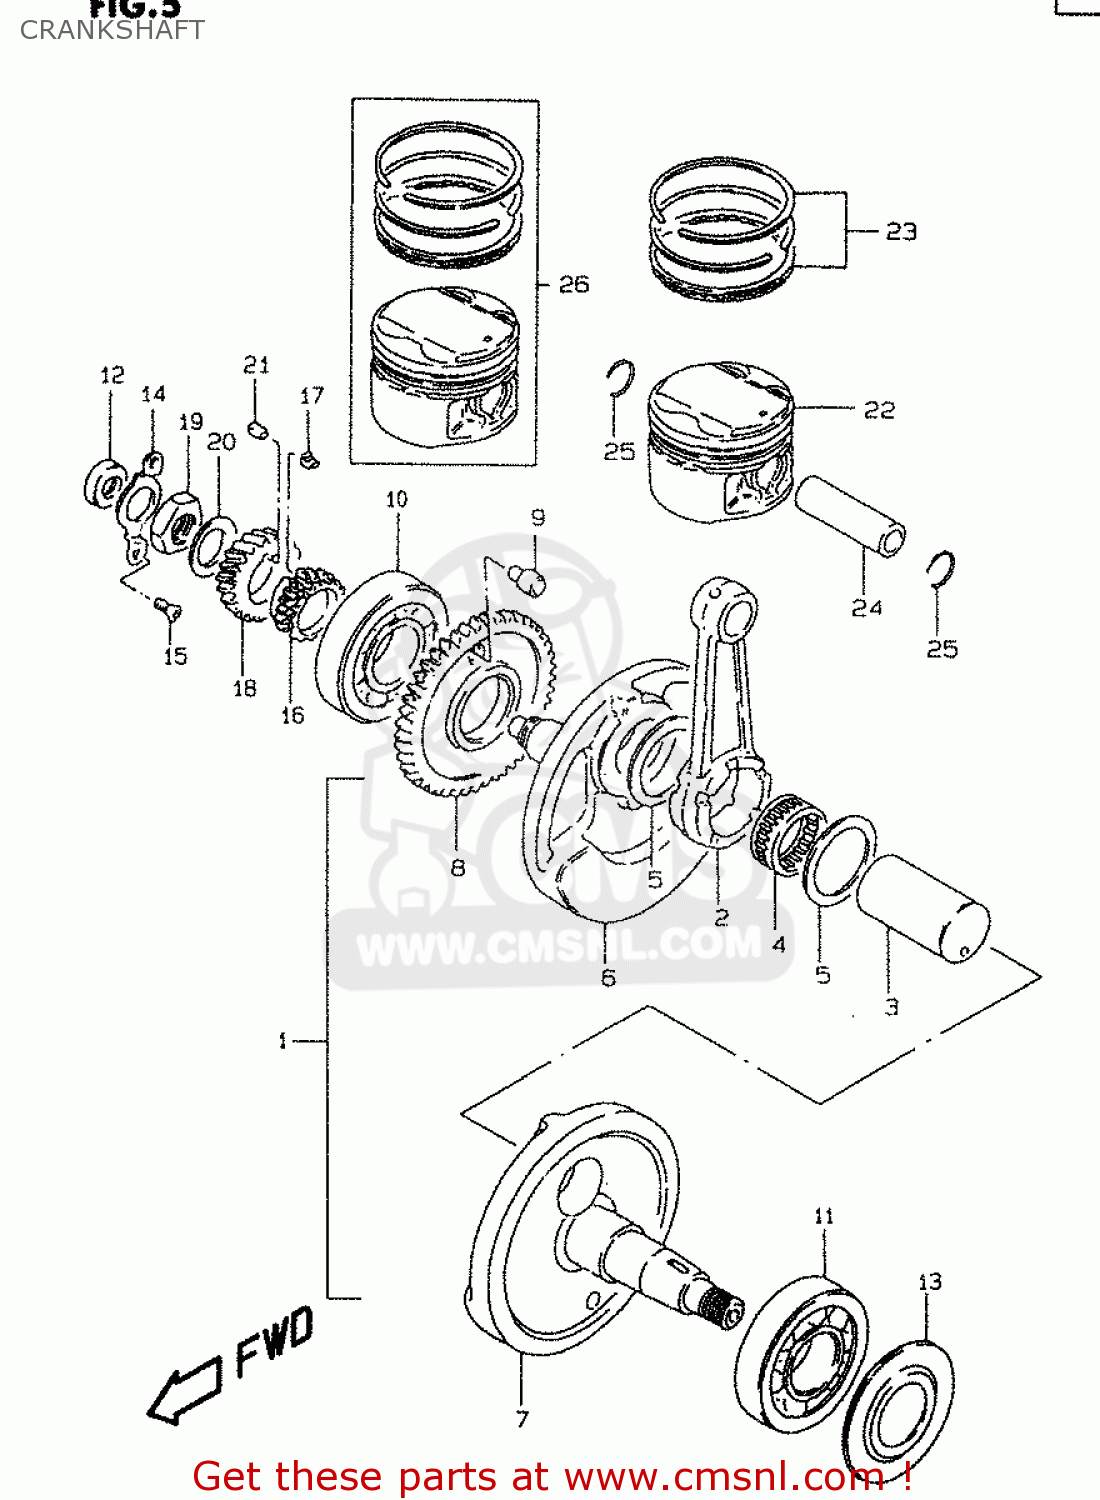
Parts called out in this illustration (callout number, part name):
1	CRANKSHAFT ASSEMBLY
2	ROD,CONNECTING
3	PIN,CRANK
4	BEARING(31X39X21)
5	WASHER(31X48.5X1)
6	CRANKSHAFT,R
7	CRANKSHAFT,LEFT
8	GEAR,CRANK BALANCER DRIVE
9	PIN
10	BEARING(30X72X19)
11	BEARING(35X80X21)
12	SEAL,OIL(14X26X6)
13	WASHER,CRANKSHAFT OIL SEALING
14	RETAINER,CRANKSHAFT BEARING,R
15	SCREW
16	SPROCKET,CAM CHAIN DRIVE(NT:21
17	KEY,SPROCKET
18	GEAR,PRIMARY DRIVE NO.21
19	NUT (20MM)
20	WASHER
21	KEY
22	PISTON
23	RING SET,PISTON
24	PIN,PISTON
25	CIRCLIP,PISTON PIN
26	PISTON SET(OS:0.5)
